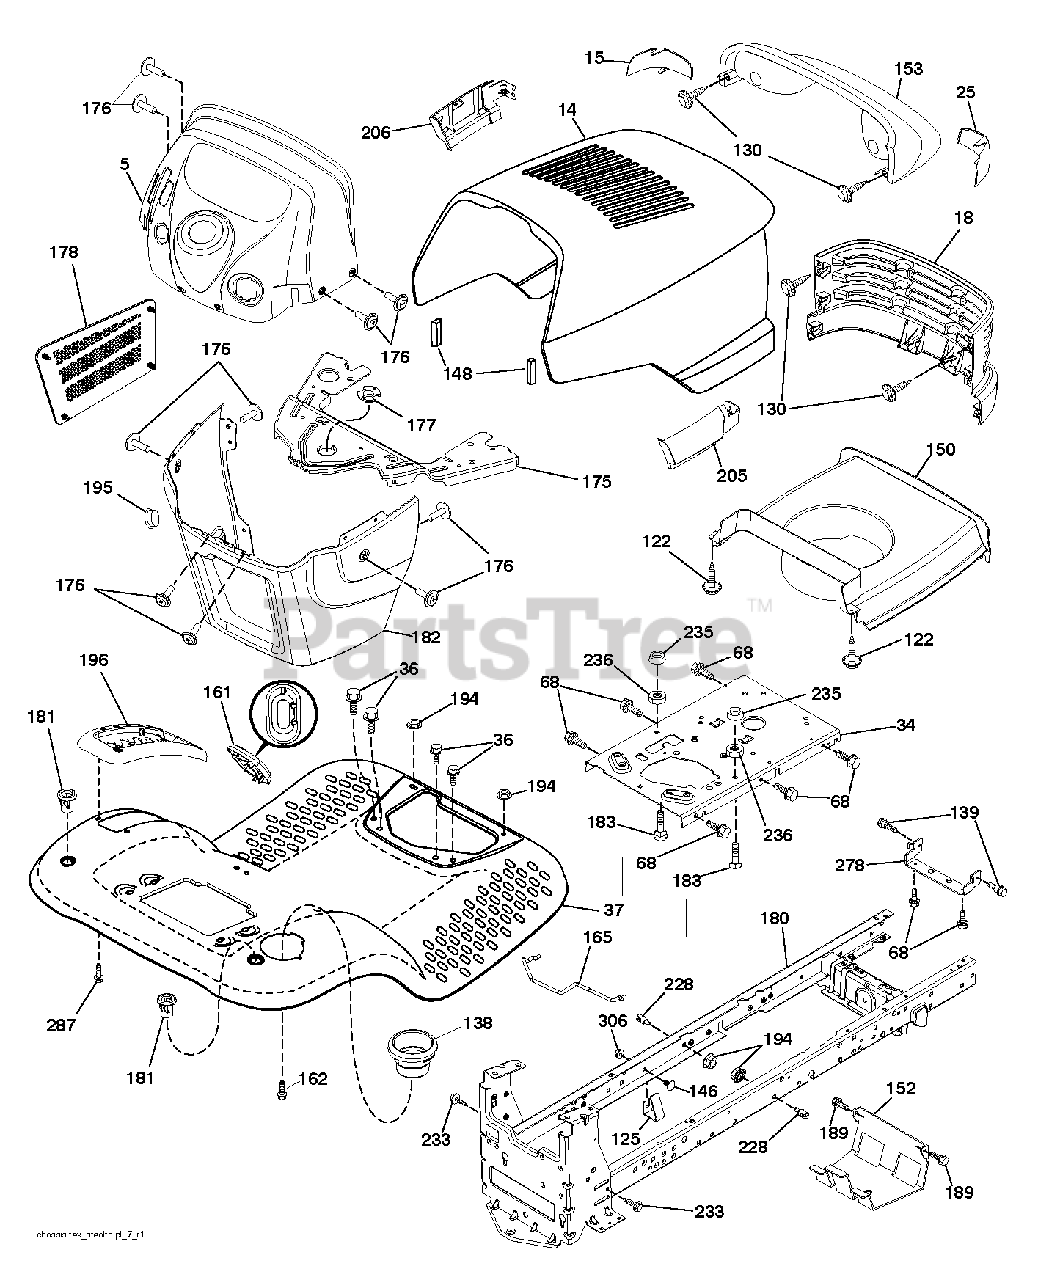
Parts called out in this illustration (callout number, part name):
5	DASH.UPR.STEALTH
15	LENS LH
18	GRILLE.STEALTH.GT.BLACK
25	LENS RH
37	FENDER.TLT.W/CPH.W/FW.666
68	SCREW LT
122	SCREW.WSHD.HEX10-32X5/8
130	SCREW.#10 X 0.750.BOS THREAD
138	CUPHOLDER.TL.TEX.BLACK
148	EXTRUSION BUMPER
150	DUCT HEAT HOOD
152	SHIELD BROWNING
161	WINDOW.FUEL.LT.TEX.BLACK
162	SCREW.HI-LO.CONSOLE
165	SUPPORT.TANK.REAR.W/TE
175	CROSSMEMBER.
176	SCREW.#10-24X5/8.RN.QU
177	BUSHING,STEERING
178	CARGO.ASM.NET.DASH.LOWER
180	CHASSIS
182	DASH.LOWER.
183	BOLT.5/16-18X1-1/4 FULL THD
194	NUT LOCK HEX FLANGE 5/16-18
196	CONSOLE.ASM.DECKLFT.BL/RBT.TLT
205	SKIRT.GRILLE.STEALTH.RH
206	SKIRT.GRILLE.STEALTH.LH
228	STUD.FASTNER.W/ANTI-ROTATE
233	BOLT.SHOULDER
235	SPACER FENDER
236	NUT.CENTERLOCK.5/16-
278	BRKT.HOOD/MUFF.STEALTH
